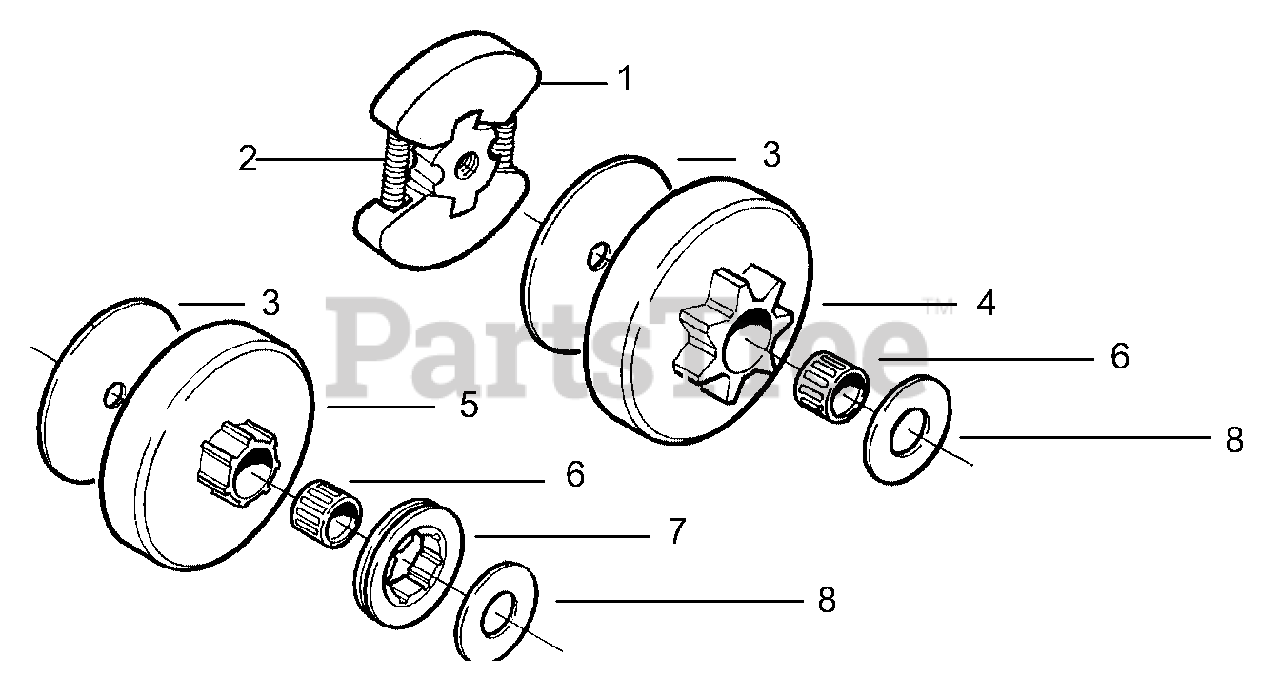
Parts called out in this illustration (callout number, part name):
1	Clutch Assembly
2	Spring - Clutch
3	Clutch Washer
4	Clutch Drum w/Bearing Ass'y.
5	Drum, Adapt. & Bearing Kit
6	Clutch Bearing
7	Rim-Floating (.325)
8	Thrust Washer
